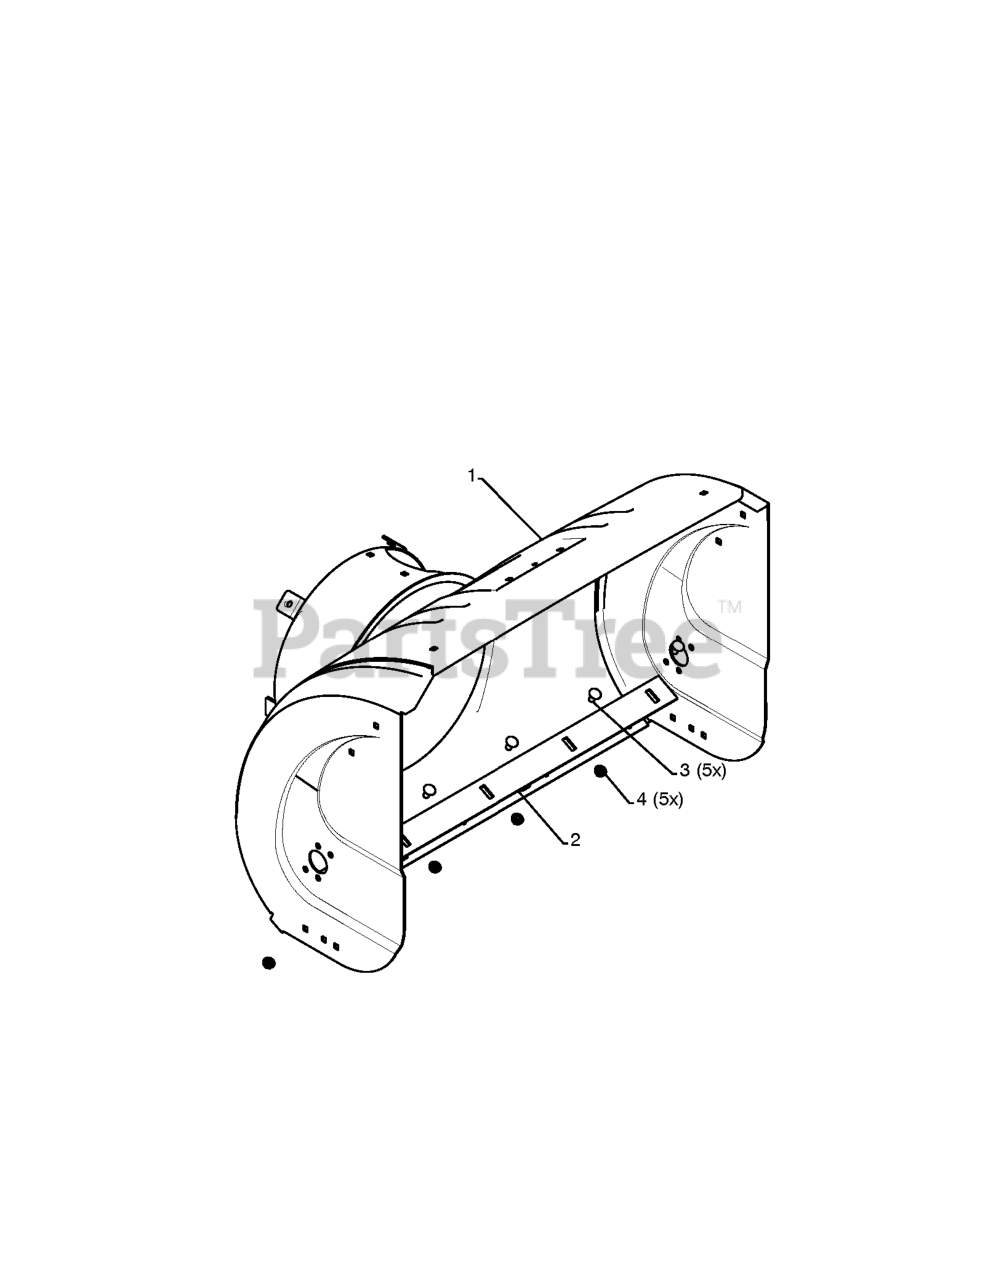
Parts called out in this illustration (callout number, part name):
1	HOUSING.AUG.WELDMENT.30.ORANGE
2	BAR.SCRAPER.30.BLACK
3	BOLT
4	NUT.FLANGE.5/16
